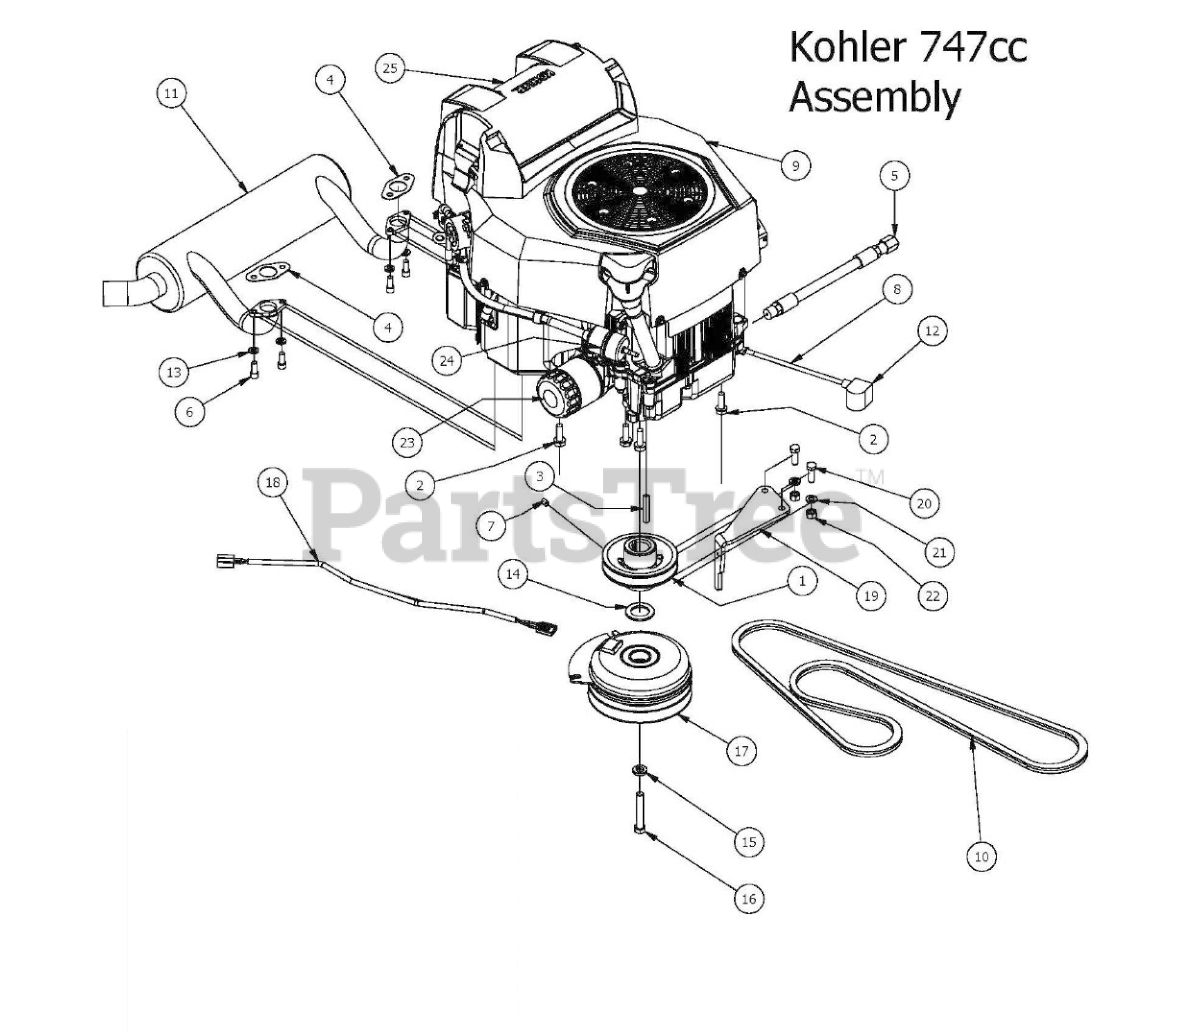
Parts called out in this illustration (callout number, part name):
1	4 3/4 Motor Pulley
2	3/8 x 1 1/8 bolt
3	1/4 x 2 Square key Stock
4	Exhaust Gasket
5	Oil drain Valve
6	5/16-18 x 3/4 Socket C/S
7	5/16 Set Screw
8	Ground Cable
9	Kohler-2014 CZT/Outlaw 747cc
11	2014 Kohler Outlaw Muffler
12	Black Boot For Ground Cable
13	5/16" Lock Washer
14	1 1/8" Flat Spacer
15	7/16" Lock Washer
16	7/16" x 2 1/2" Hex Bolt
17	Clutch Assembly
18	Clutch Pigtail
19	PTO Engager Holder
20	3/8" x 1" Hex Bolt
21	3/8" Lock Washer
22	3/8" Hex Nut
23	725 & 747 Kohler Oil Filter
24	Universal Inline Fuel Filter
25	747 Kohler Air Filter
